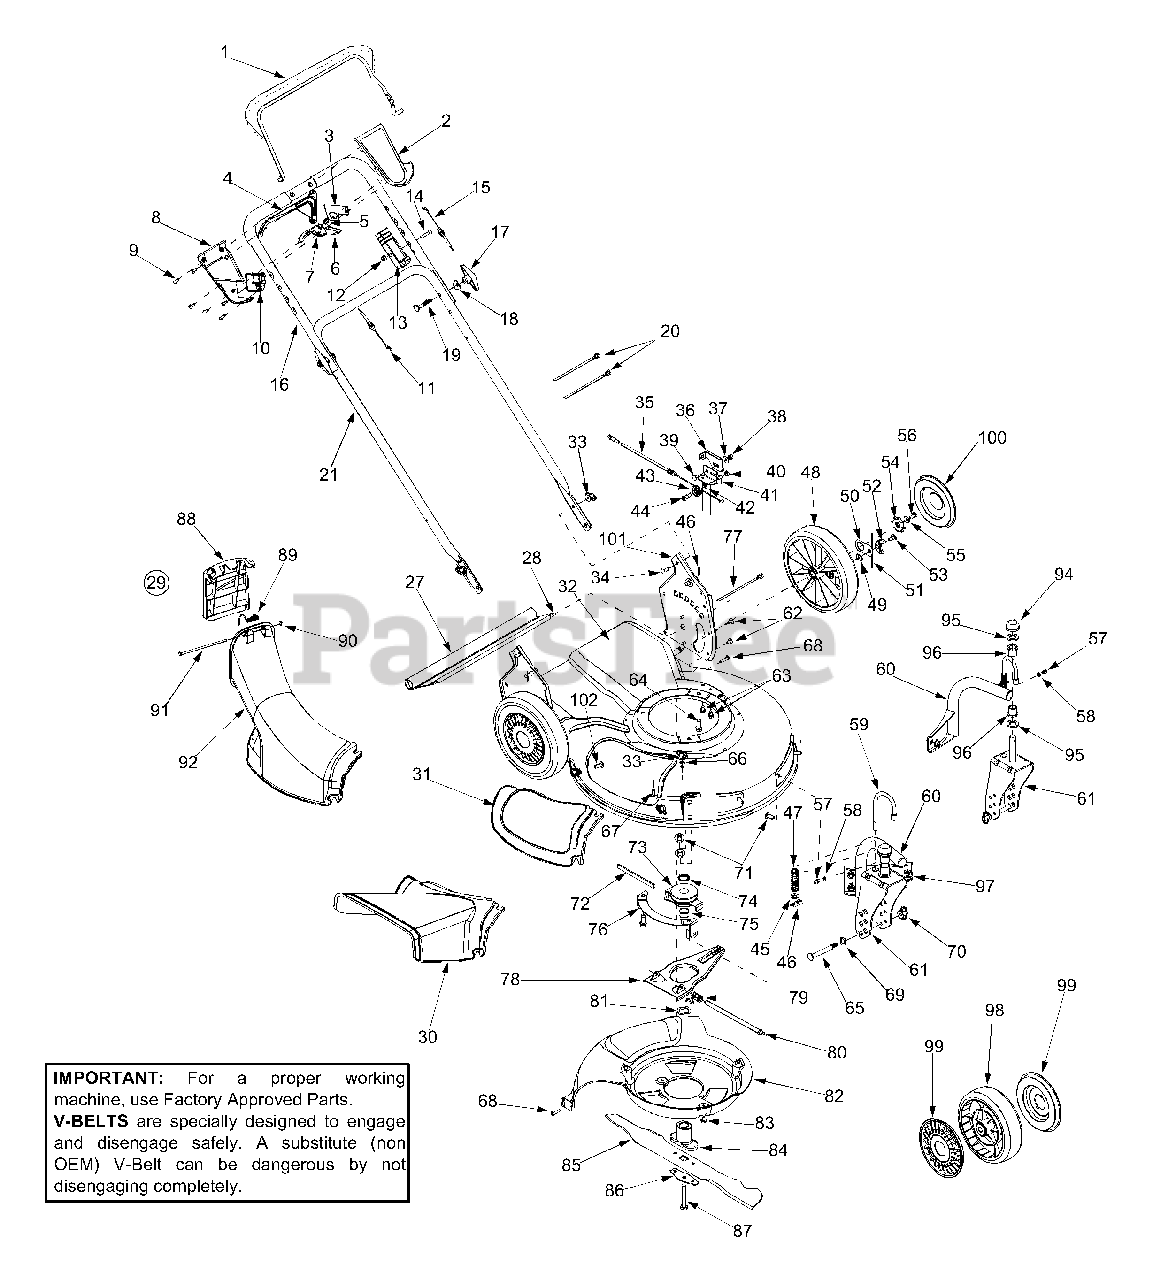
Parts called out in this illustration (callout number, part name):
1	Control Handle
2	Upper Control Housing
3	6 Spd. Rack Cable Bracket
4	Control Lever
5	Gear Insert
6	Shift Lever Spring
7	6 Speed Shift Lever
8	Lower Control Housing
9	C Sunk Tap Screw #10 x.75 Lg
10	Cable Mounting Cap
11	Drive Cable 51.0
12	Top Lock Nut 1/4-20
13	Control Housing
14	Oval C-Sunk Screw
15	Control Cable 47"
17	Wing Nut
18	Saddle Washer.320 ID x.830 OD
19	Carriage Bolt 5/16-18 x 2.0
20	Cable Tie
27	Trail Shield
28	Trail Shield Wire
29	Chute Assembly
30	Side-Discharge Chute
31	Mulch Cover
34	Carriage Bolt 1/4-20 x.75
35	6 Speed Cable
38	Hex Nut 1/4-20
39	Carriage Screw 1/4-20 x.50
40	Hex Nut 1/4-28
43	Cable Roller
44	Shoulder Screw.375 ID x 1/4-14
45	Flat Washer.330 ID x.630 OD
46	Cotter Pin
47	Compression Spring
48	Wheel 9 x 2
49	Top Lock Tab Weld Nut 1/4-20
50	Ratchet Pawl Plate
51	Plastic Spring Ratchet
52	Pawl RH
53	Shld Screw.340 ID x.285 OD
54	Wheel Rachet
55	Bell Washer.265 ID x.75 OD
56	Hex Cap Screw 1/4-20 x.620
57	Grease Fitting
58	Flat Washer.203 ID x.403 OD
59	Wheel Pin Lock
62	Screw 1/4-14 x.500
63	Screw 1/4-20 x.625
64	Hex Washer Screw 3/8-16 x 1.0
65	Caster Axle
66	Push Nut.25ID x.50OD
67	Carriage Screw 1/4-20 x.75
68	Screw #12-16 x 1.00
69	Wave Washer.531 ID x.781 OD
70	Wing Nut
71	Carriage Bolt 5/16-18 x.62
72	Belt 3/8 x 39.24
73	Pulley Assembly
74	Sleeve Spacer.88 ID x 1.13 OD
75	Sleeve Spacer.88 ID x 1.00 OD
77	Cable Tie
80	Pivot Shaft
81	Wave Washer 1.38 ID x.88 OD
82	Baffle
83	Screw 1/4-20 x 3.75
84	Blade Adapter
85	21" Mulching Blade
86	Blade Bell Support
87	Hex Bolt 3/8-24 x 2.5
88	Chute Door
89	Torsion Spring
90	Push Cap
91	Pivot Rod
92	Discharge Chute
94	Push Cap
95	Flat Washer.640 ID x 1.12 OD
96	Flange Bearing
97	Flange Lock Nut 5/16-18
98	Wheel 7 x 2
99	Hubcap - Spoke w/ Hole
100	Hubcap - Radial Spoke
